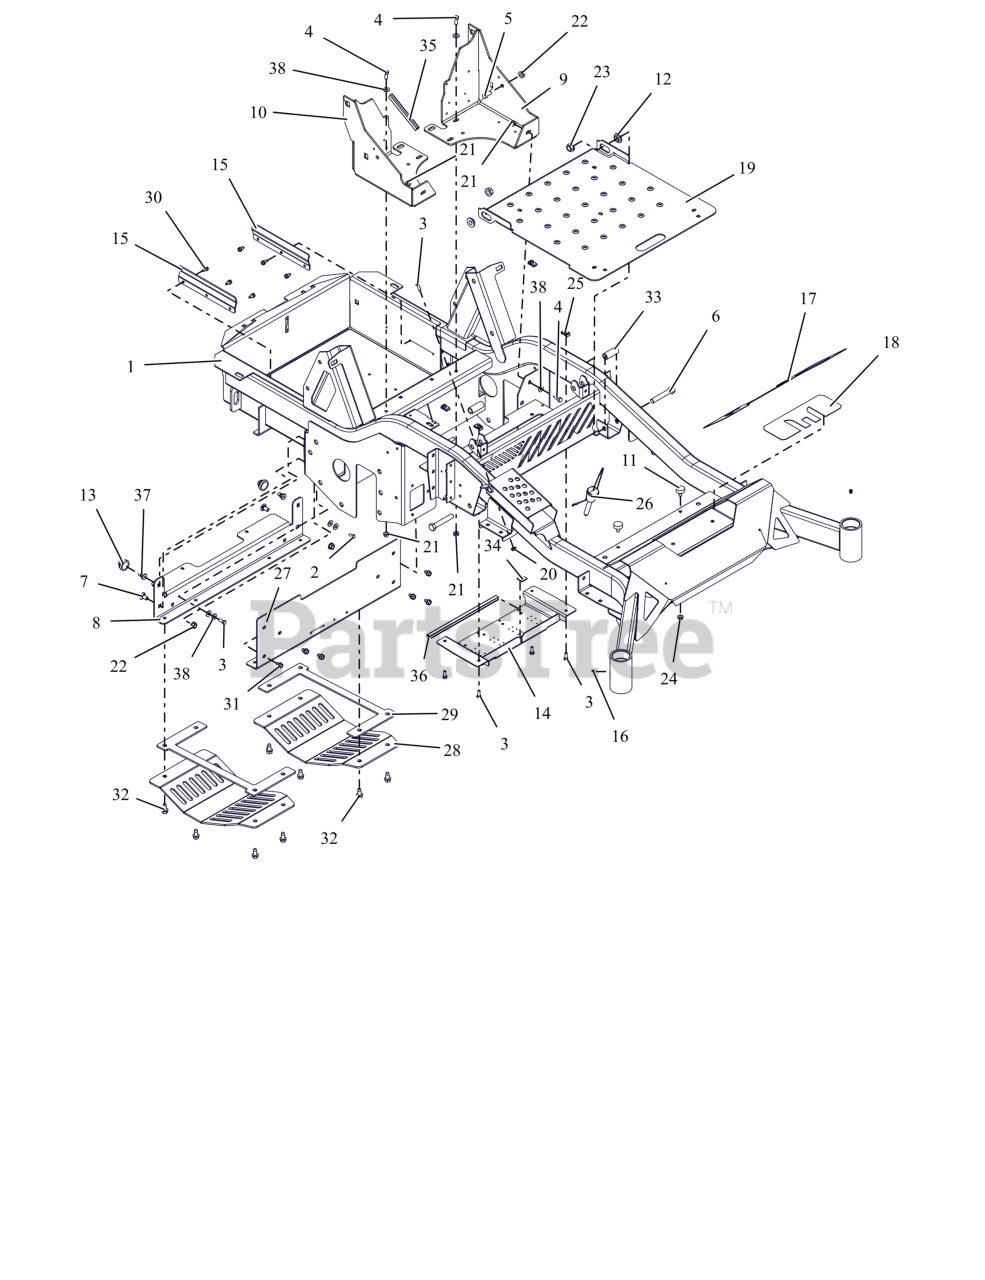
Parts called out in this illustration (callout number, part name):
1	KIT,EV FRAME(LG)W/DECALS-A
2	BLT,HEX .25-20X.50 G5 ZCC
3	BLT, HEX .25-20X.75 G5 ZCC
4	BLT,HEX .31-18X.75 G5 ZCC
5	BLT,HEX .38-16X.75 G5 ZCC
6	BLT, HEX .50-13X3.00 G5 ZCC
7	BLT, RHSSN .38-16X.75 G5 ZCC
8	BRKT, SKID PLATE MTG. (ORANGE)
9	BRKT, SUPPORT ROPS -LH (ORANGE)
10	BRKT, SUPPORT ROPS-RH (ORANGE)
11	BUMPER, RUBBER
12	BSHG-FLG .515X.750X.395X1.120
13	COUPLING, RUBBER PUSH-IN
14	COVER, BOTTOM ACCESS -OPEN (ORANGE)
15	DEFLECTOR, BATTERY -EV (ORANGE)
16	FTG, .25-28 FLUSH MNT GREASE
17	GRIP, FRONT
18	GRIP, TAPE FRONT
19	PANEL, ACCESS
20	NUT-LK-CTR-FLG .25-20 ZC120
21	NUT,LK-CTR-FLG .31-18 GF ZCC
22	NUT-LK-CTR-FLG .375-16 GF ZCC
23	NUT-LK-CTR-FLG .500-13 GG ZCC
24	NUT,SPNLK-FLG .31-18 G5 ZCC
25	NUT-RTNR .25-20X.56
26	PIN- MAGNETIC .50X2.70
27	PLATE, FRONT FRAME (ORANGE)
28	PLATE, SKID (BLACK)
29	PLATE, SKID TENSION (BLACK)
30	SCR-TAP .25-20X.50 HWH ZCC
31	SCR,TAP .312-18X.50 HWH TR ZCC
32	SCR,TAP .375-16X.75 HWH TR ZCC
33	SPACER, .515X.75X1.83
35	STRIP, COWL
36	STRIP, COWL
37	STUD, BALL FEMALE .250-20 THREAD
38	WSHR, FLT .312X.734X.065 ZCC
